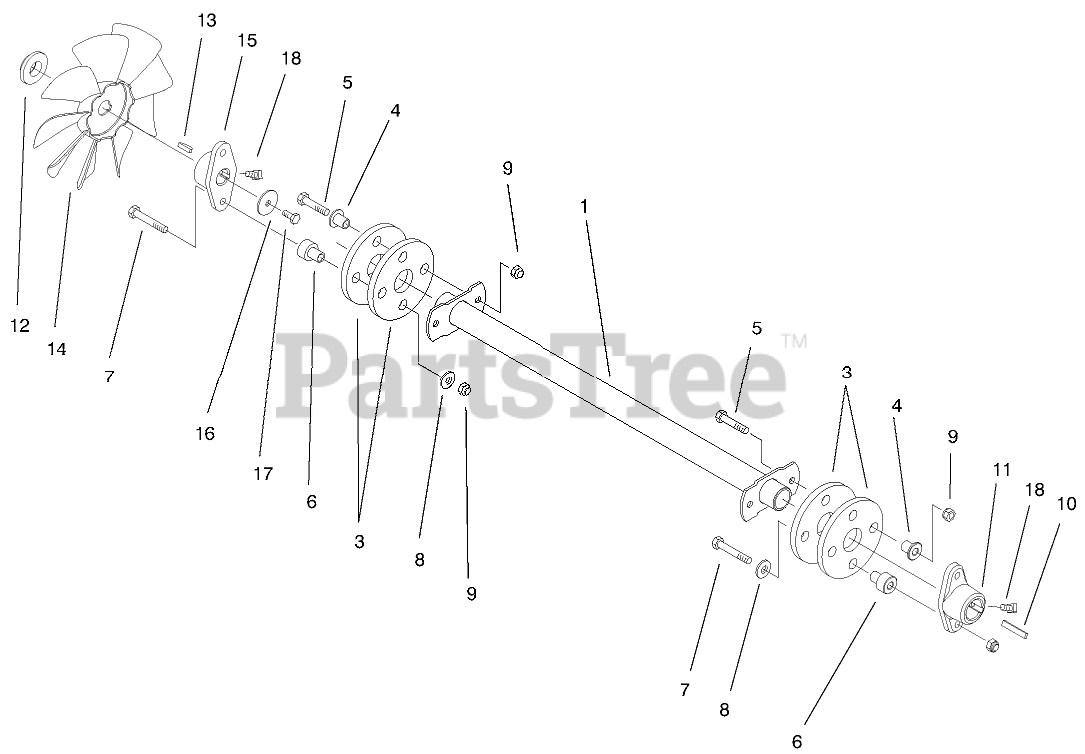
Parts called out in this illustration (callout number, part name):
1	SHAFT-DRIVE
3	COUPLING-RUBBER
4	SPACER
5	SCREW-HH
6	SPACER
7	SCREW-HH
8	WASHER-FLAT
9	NUT-LOCK, NI
10	KEY-SQUARE
12	SPACER-FAN
13	KEY-WOODRUFF
14	FAN-HYDRO
16	WASHER
17	SCREW-HH
18	SCREW-SET
